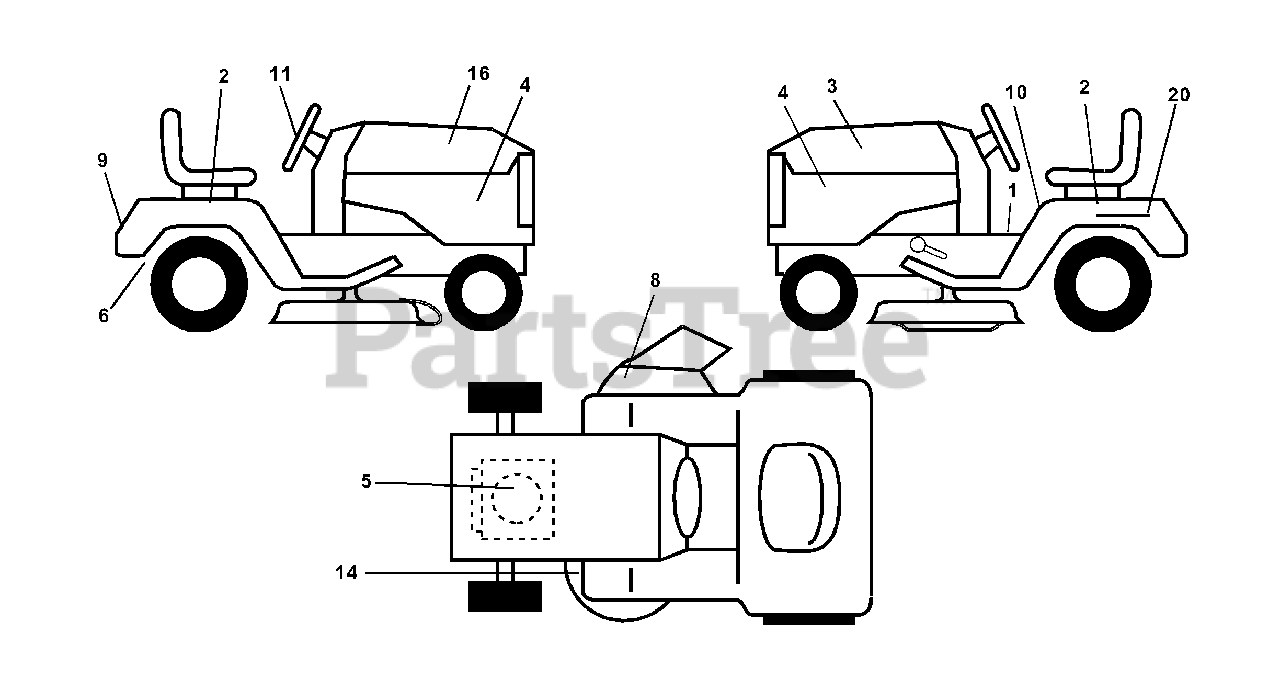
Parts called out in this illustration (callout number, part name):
1	Decal Oper
2	Decal Fender Auto
3	Decal Hood LH
4	Decal Side Panel Logo
5	Decal HP Engine
6	Decal By Pass Lt Hydro
8	Decal Mower Warn Keep Hand Away
9	Decal Fender Logo
10	Decal Fender Danger E/F
11	Decal Ins Strg Whl
14	Decal V-Belt Schematic
16	Decal Hood Rh
20	Decal Bat Dan/Psn
